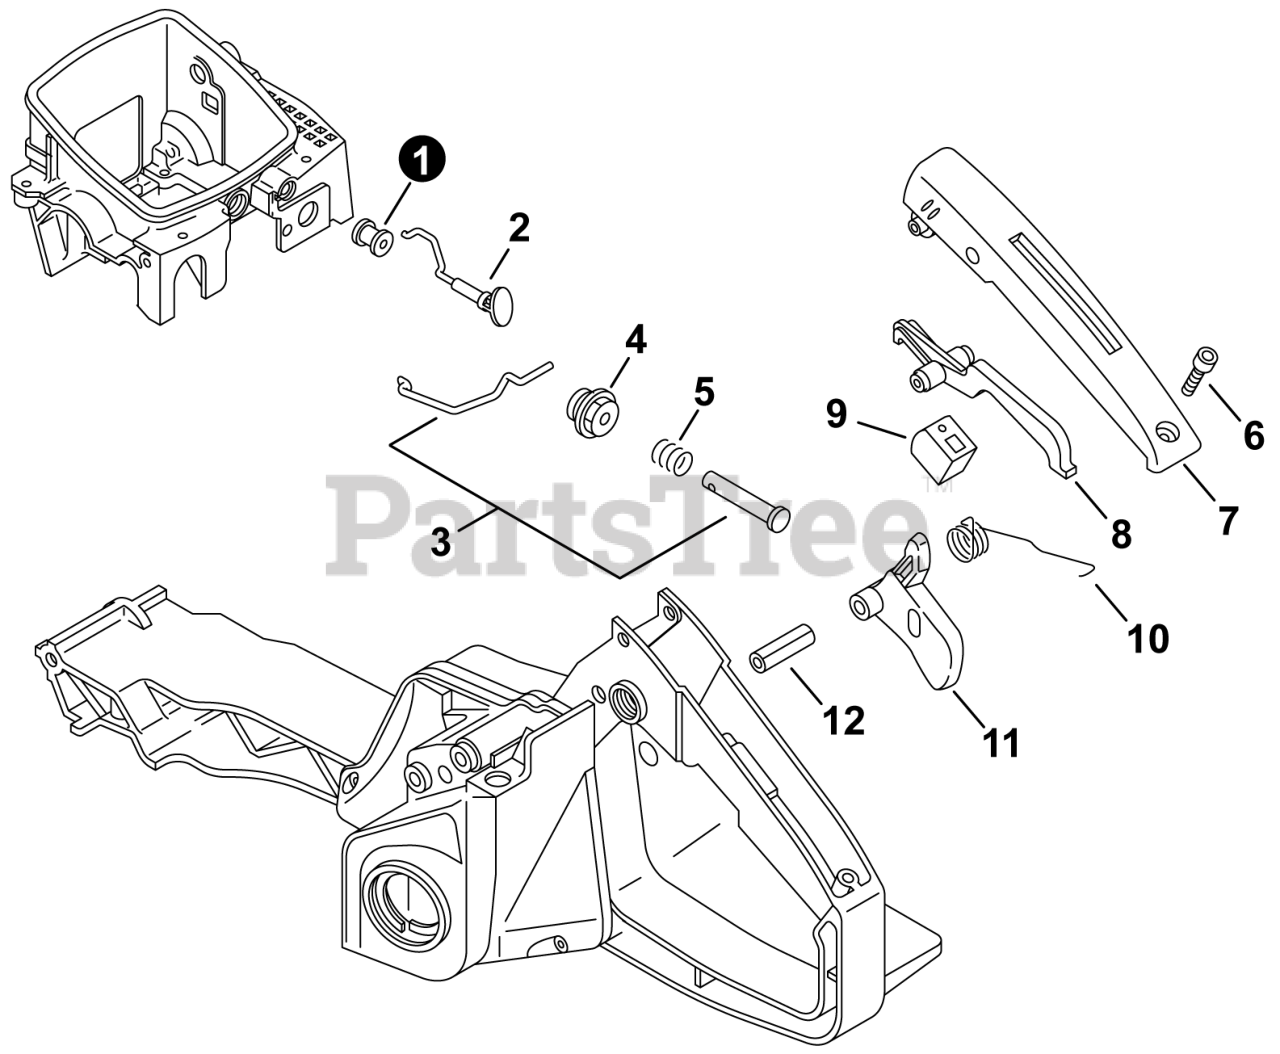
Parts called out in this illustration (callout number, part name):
1	GROMMET, CHOKE
2	ROD, CHOKE
3	THROTTLE ROD KIT
4	GROMMET, THROTTLE ROD
6	BOLT 4×14
7	COVER, HANDLE
8	LEVER, THROTTLE LOCKOUT
9	CUSHION, THROTTLE
10	SPRING, THROTTLE RETURN
11	TRIGGER, THROTTLE - BLACK
12	PIN, SPRING Ø5×25 MM
